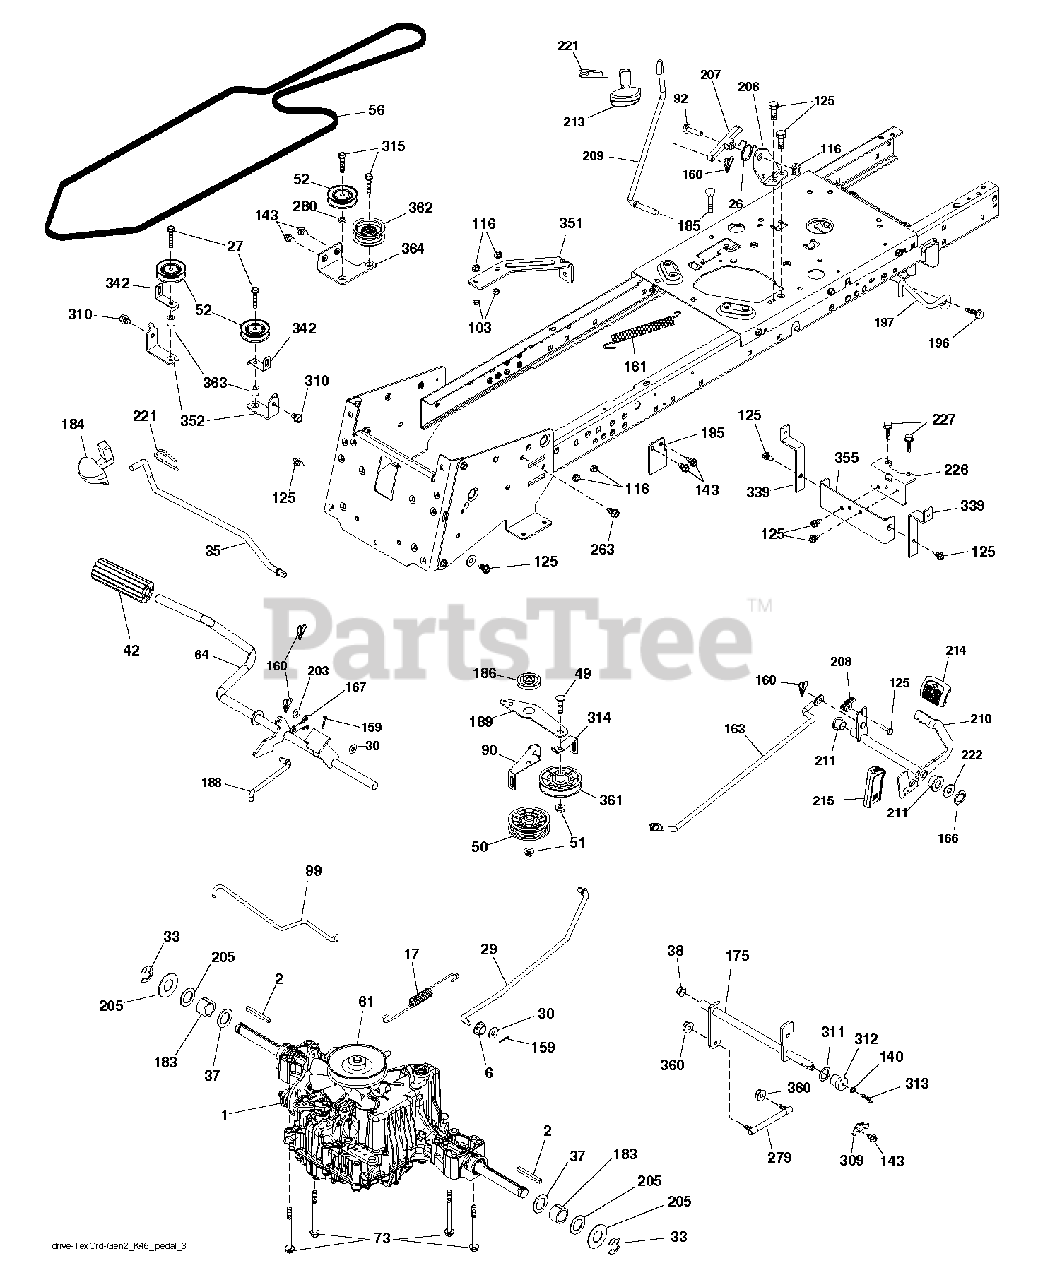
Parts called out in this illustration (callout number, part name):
2	SQUARE KEY
6	BUSHING.SNAP.NYL.BLK.
17	SPRING
26	SPRING.RETURN.CRUISE
29	ROD ROD BRAKE K46 TCRD GEN 2
30	WASHER
35	ROD.BRAKE.PARTK.HUSQ.TEX
38	NYLINER SNAP 5/8" ID
42	PEDAL COVER T
50	IDLER.FLAT.910.OFFSET
51	NUT LOCK FLG 3/8-16 UNC
52	PULLEY.V-IDLER.
56	BELT BELT DRIVE GROUND 114.25
61	PULLEY PULLEY INPUT FLANGED TR
64	SHAFT.ASM.PEDAL.BRK.CNTR
73	BOLT HEX 5/16-18 GR 5
90	KEEPER KEEPER BELT CLUTCHING T
92	BOLT
99	ROD ROD BYPASS CRD TEX GEN 2
103	JAM NUT TI
116	NUT LOCK HEX FLANGE 5/16-18
125	SCREW
140	LOCKWASHER
143	SCREW LT
159	COTTER PIN
160	RETAINER CLIP
161	SPRING, RETURN LT
163	ROD ROD CONTROL SHIFT PEDAL TC
166	NUT.PUSH.625
167	LATCH.BRAKE.SPRING
175	SHAFT SUBASM.SHAFT.CROSS.SHIFT
183	SPACER AXLE
184	RB HANDLE.PARKG.BRK.HUS/PRED
186	SPACER.RETAINER
188	RP LINK.CLUTCH.GROUND.DRIVE
189	BELLCRANK BELLCRANK GROUNDDRI
196	SCREW 3/8-16X1
197	LINK.CLUTCH.ANIT-ROTAT
203	WASHER
206	BRKT.MOUNT.LATCH.CRUIS
207	LATCH.CONTROL.CRUISE
208	GEAR.SECTOR.CONTROL.CR
209	ROD.CONTROL.CRUISE.GT.
210	ROCKER.ASM.PEDAL.CONTR
211	BEARING.NYLON
213	KNOB.CONTROL.CRUSIE.HU
214	PEDAL.FORWARD.PAD.TEX
215	PEDAL RUBBER REVERSE
221	RETAINER.SPRING.CLIP.H
222	WASHER 21/32 X 1-1/4 X 10 GA.
226	BRACKET.MOUNT.TORQUE.K46.TLT
227	SCREW
263	SCREW, 3/8-16X3/4
279	LINK SUBASM. LINK AND STUD
309	PLATE.FASTENING.CROSS.SHAFT
311	WASHER NYL
312	HUB.TAPERED.ROUND.CRD
314	RETAINER KEEPER BELT
315	BOLT.5/16-18X1.25
339	STRAP STRAP TORQUE K46 CRD TE
342	BELT GUIDE
351	BRACKET BRACKET DECK SWAY
352	BRACKET BRACKET.IDLER
355	STRAP STRAP TORQUE K46 CRD TEX
360	NUT NUT HEX CENTERLOCK 5/16-24
361	IDLER.V-GROOVE.910.OFFSET
362	IDLER.FLAT.2.25.INCH
363	SPACER SPACER 343X63X.62
364	BRACKET BRACKET IDLER CRD TEX
